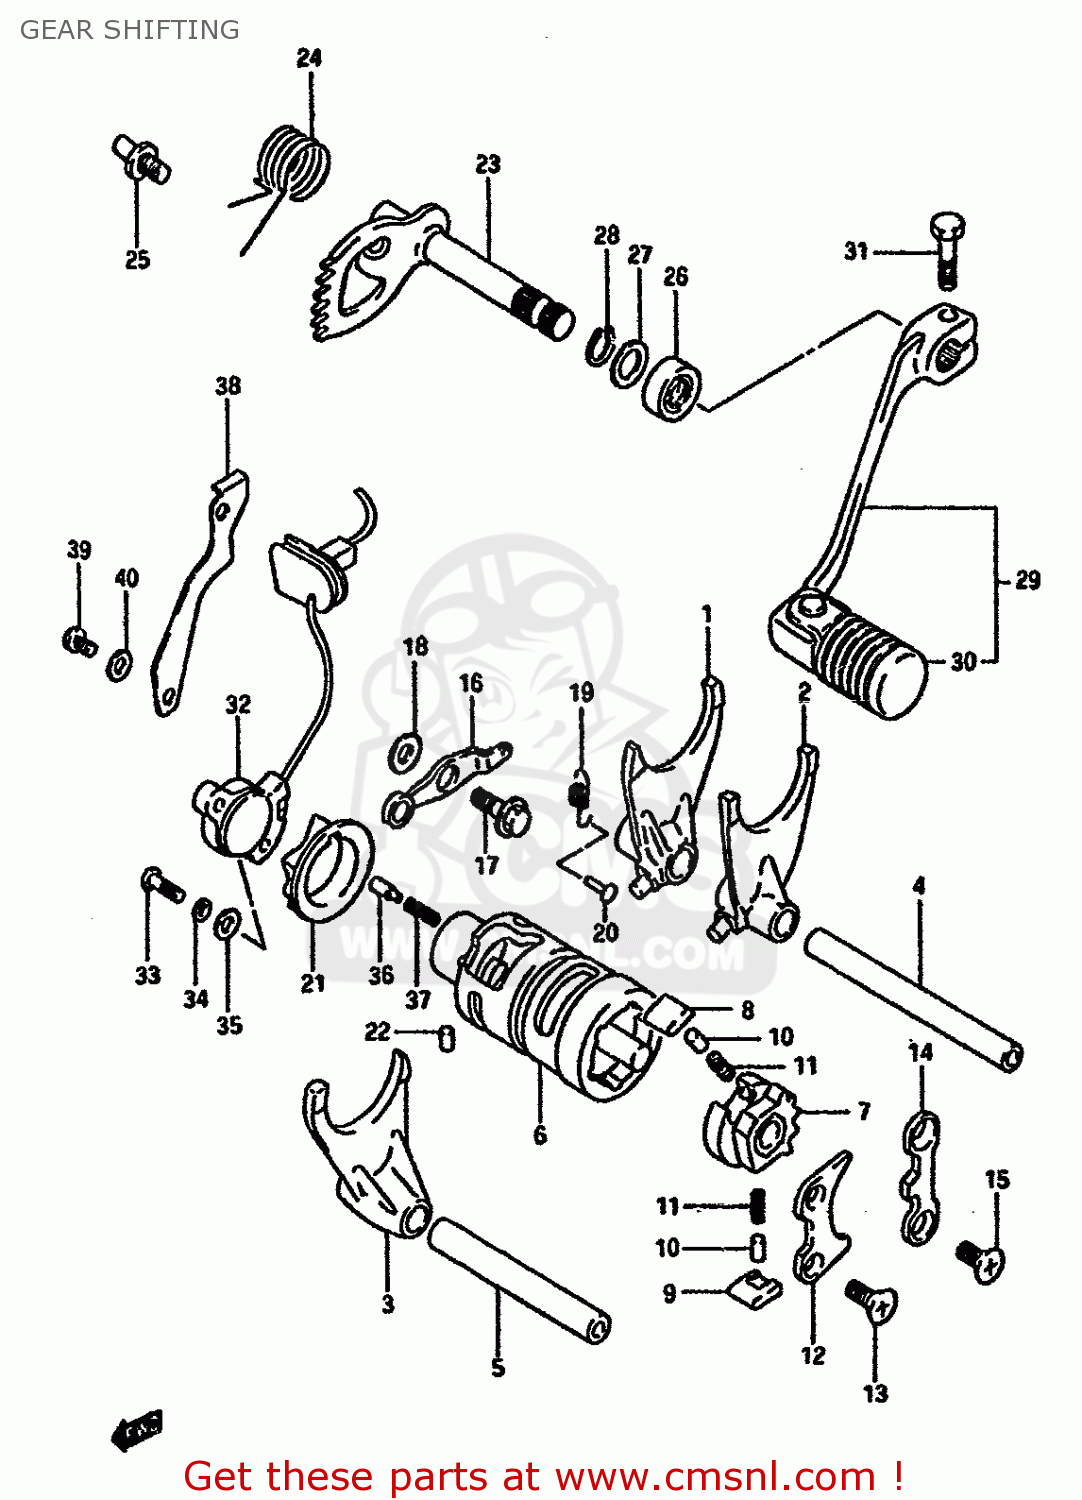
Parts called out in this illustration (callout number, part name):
1	FORK,GEAR SHIFT NO.1
2	FORK,GEAR SHIFT NO.2
3	FORK,GEAR SHIFT NO.3
4	SHAFT,GEAR SHIFT FORK
5	SHAFT,GEAR SHIFT FORK
6	CAM,GEAR SHIFT
7	GEAR,GEARSHIFT CAM DRIVE
8	PAWL,GEAR SHIFT NO.1
9	PAWL,GEAR SHIFT NO.2
10	PIN(5X8)
11	SPRING
12	LIFTER,GEAR SHAFT PAWL
13	SCREW
14	STOPPER,GEAR SHIFT POLE
15	SCREW
16	STOPPER,GEAR SHIFT CAM
17	BOLT
18	WASHER
19	SPRING
20	RIVET
21	PLATE,SHIFT CAM STOPPER
22	PIN 4X6
23	SHAFT,GEAR SHIFT
24	SPRING
25	STOPPER,GEAR SHIFT CAM
26	OIL SEAL
27	WASHER
28	CIRCLIP
29	LEVER ASSEMBLY,GEAR SHIFTING
30	RUBBER,GEAR SHIFT PEDAL
31	BOLT
32	TERMINAL BASE,NEUTRAL
33	SCREW
34	LOCK WASHER
35	WASHER
36	PIN(5X15.5)
37	SPRING
38	CLAMP,LEAD WIRE
39	SCREW
40	WASHER,LOCK
